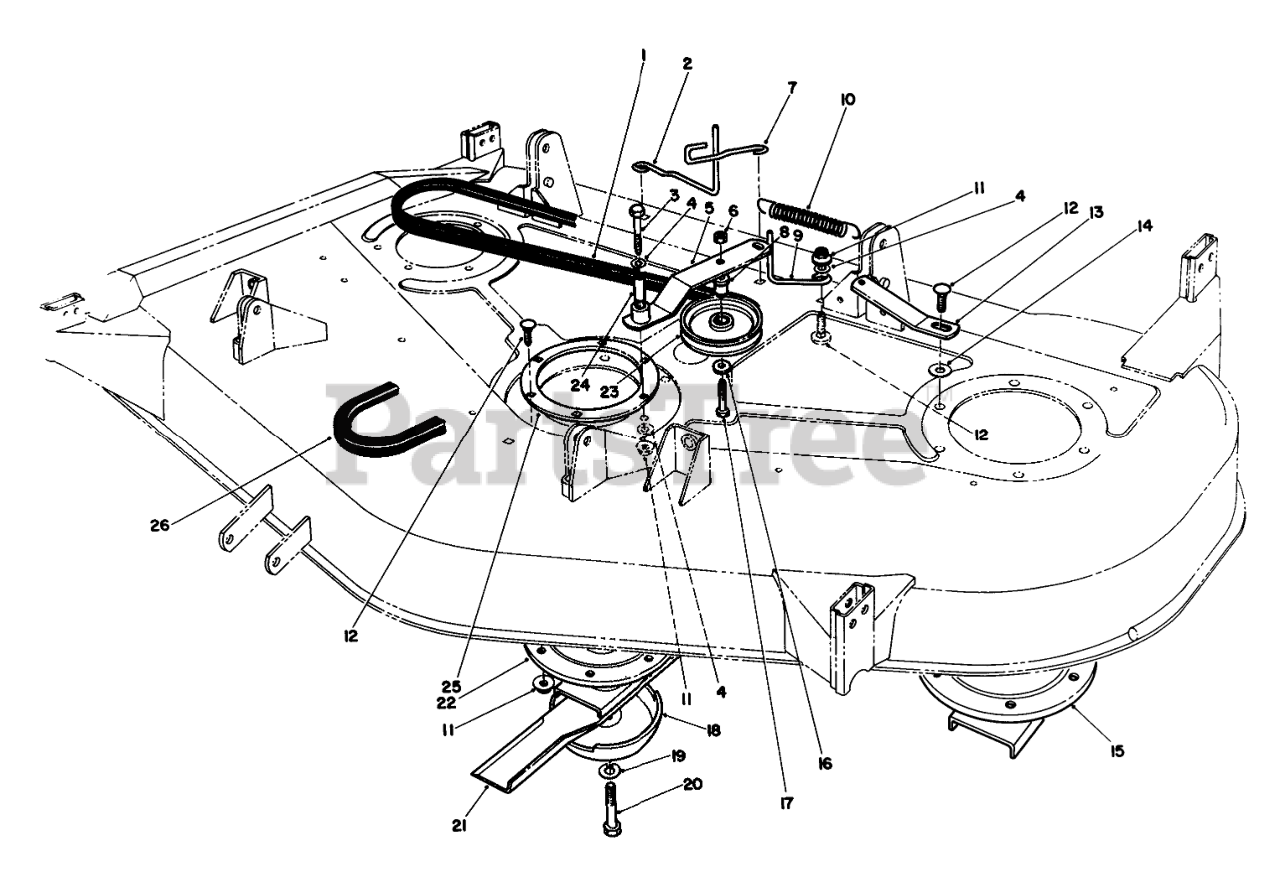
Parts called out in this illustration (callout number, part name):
1	V-BELT
2	BELT ROD
3	SCREW-HH
4	WASHER-FLAT
5	Arm-Idler
6	NUT-HEX
7	GUIDE-BELT
8	BUSHING-PULLEY
9	BELT ROD
10	SPRING-EXTENSION
11	NUT-HF
12	SCREW-CARR
13	PLATE-SPRING
14	WASHER-FLAT
15	SPINDLE ASM
16	WASHER-FLAT
17	Bolt-Special
18	Cup-Scalp
19	WASHER-LOCK
20	SCREW-BLADE
21	Blade
22	HOUSING - SPINDLE ASM
23	PULLEY-IDLER
24	SLEEVE
25	SUPPORT-DECK, RING
26	V-BELT, 52" DECK
